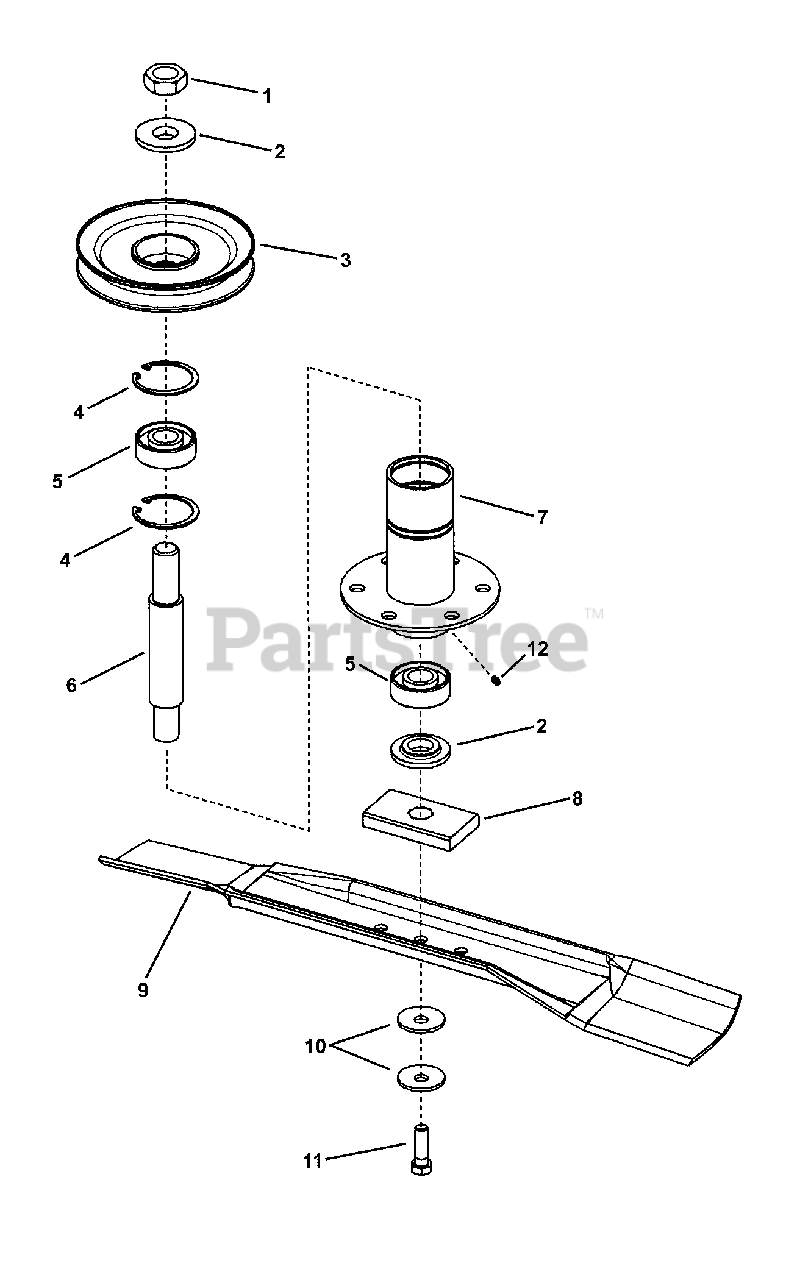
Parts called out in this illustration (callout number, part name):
1	NUT, 3/4-16 Hex Jam, GR 8
2	*WASHER, Spindle (Special)
3	PULLEY, 5-1/4" O.D. w/hub
4	*RING, 1.85" Internal Retaining
5	*BEARING, Spindle
6	*SHAFT, Blade Spindle (6.500 overall length)
7	*WELDMENT, Spindle Housing
8	*BLADE HOLDER
9	BLADE, 21" Standard Lift
10	WASHER, Cone
11	SCREW, 3/8-24 x 1-1/4" Hex Head Cap, GR 5
12	*LUBE FITTING, 3/16" Press-In
